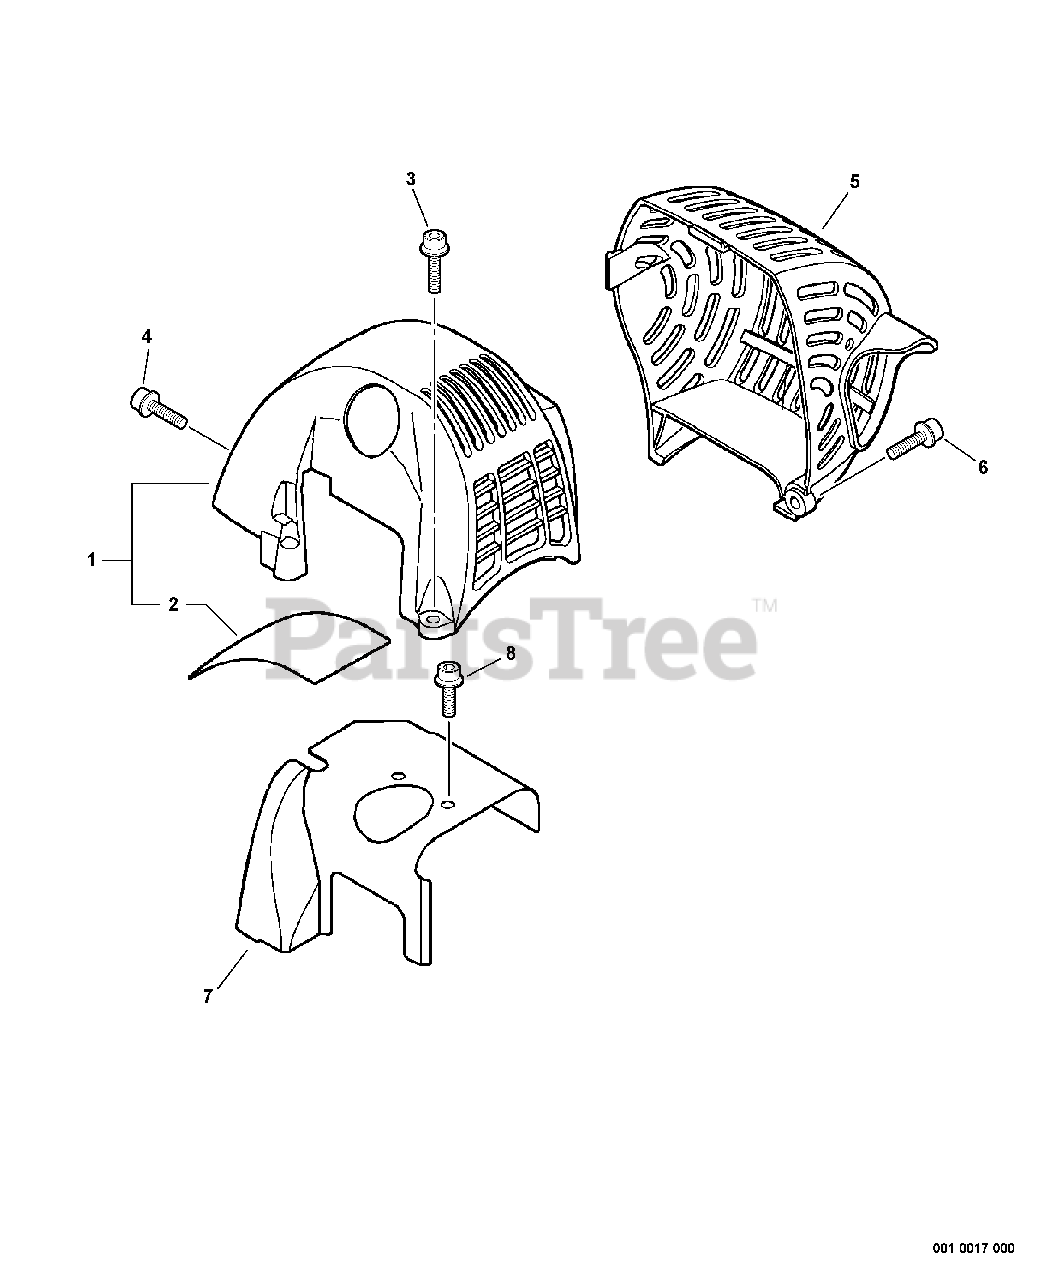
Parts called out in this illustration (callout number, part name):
1	COVER ASSY, CYLINDER
2	INSULATOR
3	BOLT 5×14
4	BOLT 4×12
5	COVER, MUFFLER
6	BOLT 5×20
7	SHIELD, CYLINDER
8	BOLT 5×8
